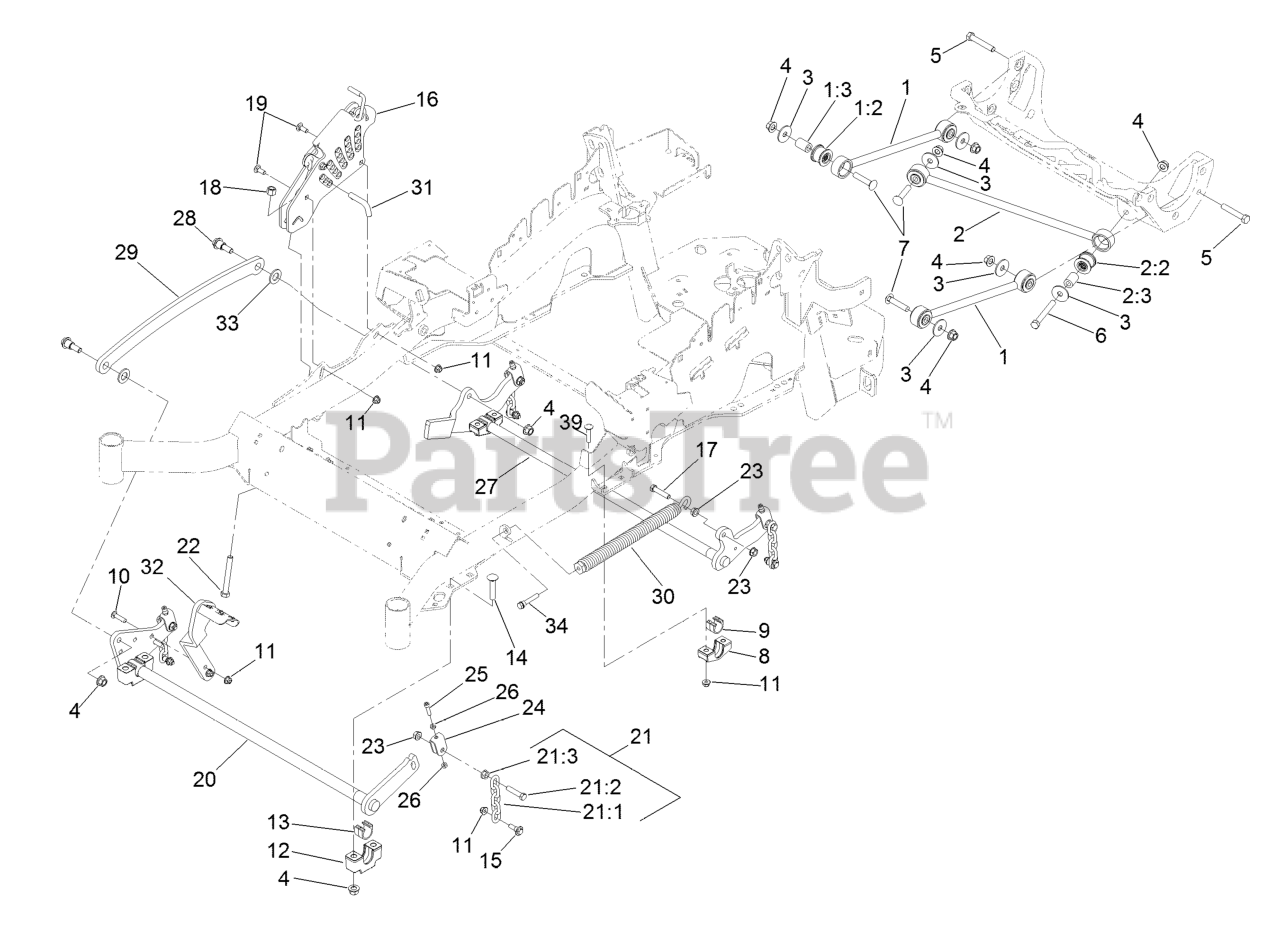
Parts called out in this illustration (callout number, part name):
1	DECK STRUT ASM
1:2	BUSHING-SUSPENSION, RUBBER
2	PANHARD ROD ASM
2:2	BUSHING-SUSPENSION, RUBBER
3	WASHER-THRUST
4	Nut-Lock 1/2-13
5	SCREW-HH
6	SCREW-HH
7	SCREW-CARR
9	BEARING-CROSS SHAFT, REAR
10	SCREW-CARR
11	NUT-HF, NI
12	SUPPORT-CROSS SHAFT, BEARING
13	BEARING-CROSS SHAFT, FRON
14	Bolt-Carriage 1/2-13 X 2 1/2 Spl Neck
15	SCREW-SHOULDER, HHF
16	HOC ASM
17	SCREW-HH
18	NUT-LOCK, NI
19	BOLT-CARR
21	DECK LIFT CHAIN ASM
21:1	CHAIN-LIFT, DECK
21:2	SCREW-HH
22	BOLT-TAP
24	YOKE-ADJUST, DECK
25	SCREW-HH
26	NUT-JAM
27	LIFT-DECK, REAR
28	SCREW-SHOULDER, HHF 1/2-13 X 1.12
29	LINK-LIFT, DECK
30	SPRING-EXTENSION
31	PIN-HOC
32	LEVER-FOOT
33	WASHER-FLAT
34	BOLT-SHOULDER
39	SCREW-CARR
